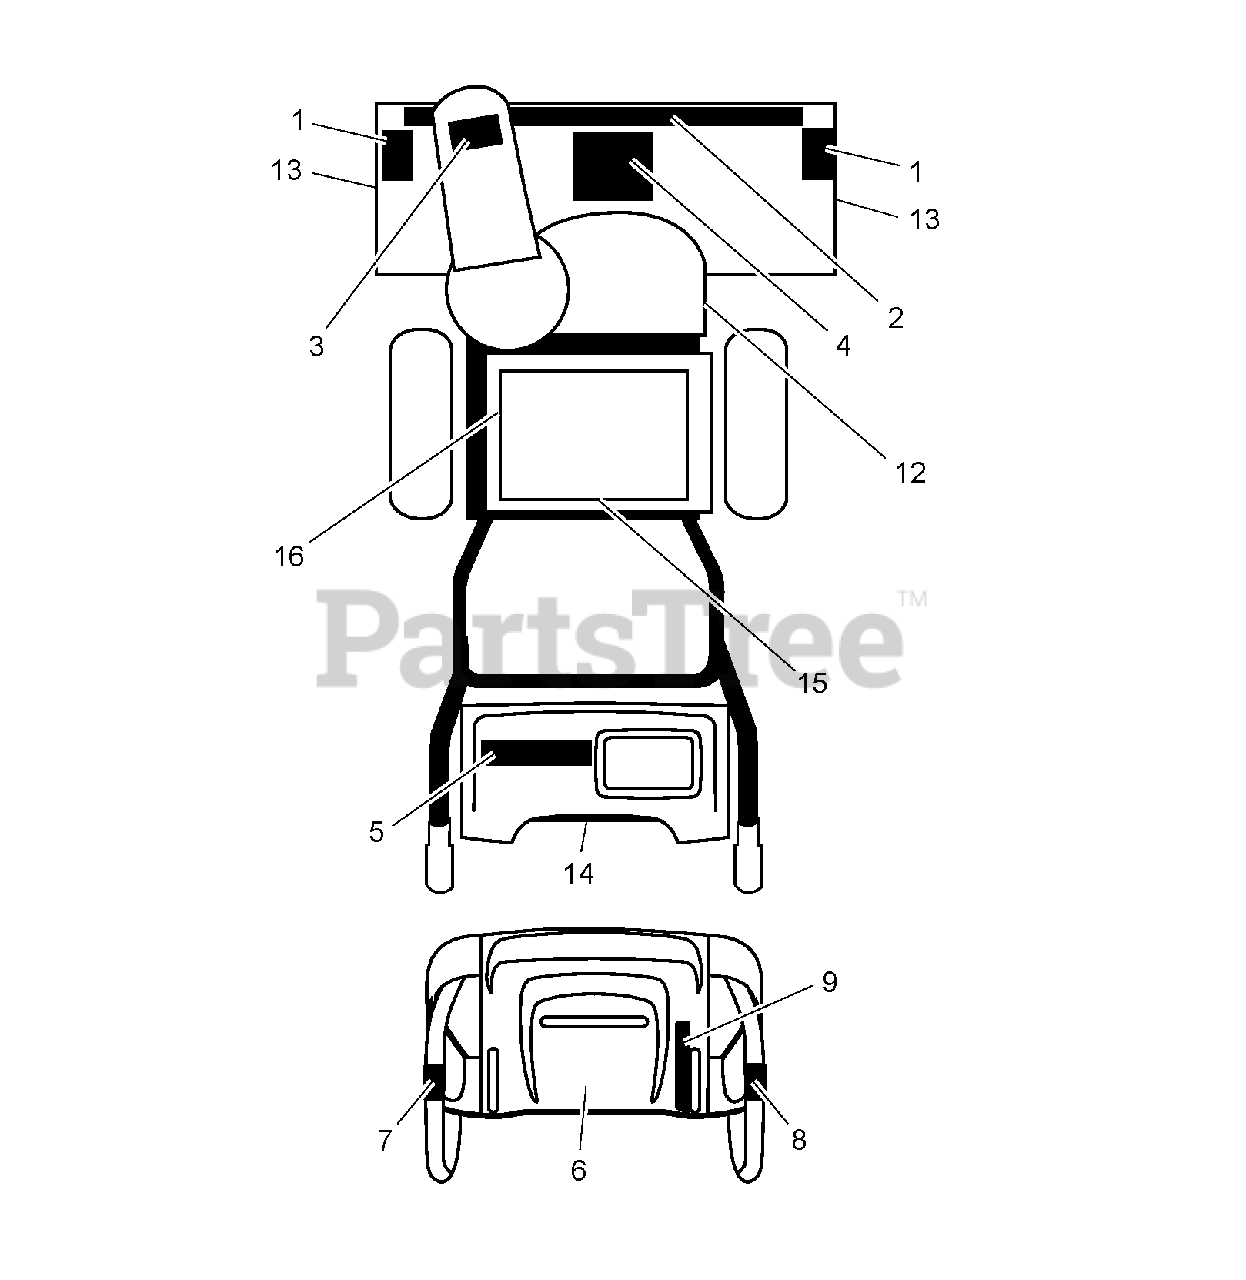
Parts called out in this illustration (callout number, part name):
1	DECAL.AUGER.SAFETY.
3	DECAL.CHUTE.SAFETY.
4	DECAL.AUGER."
6	DECAL.CONSOLE.INSTRUCTION
12	DECAL.BELT.GUARD.
14	DECAL.FENDER
